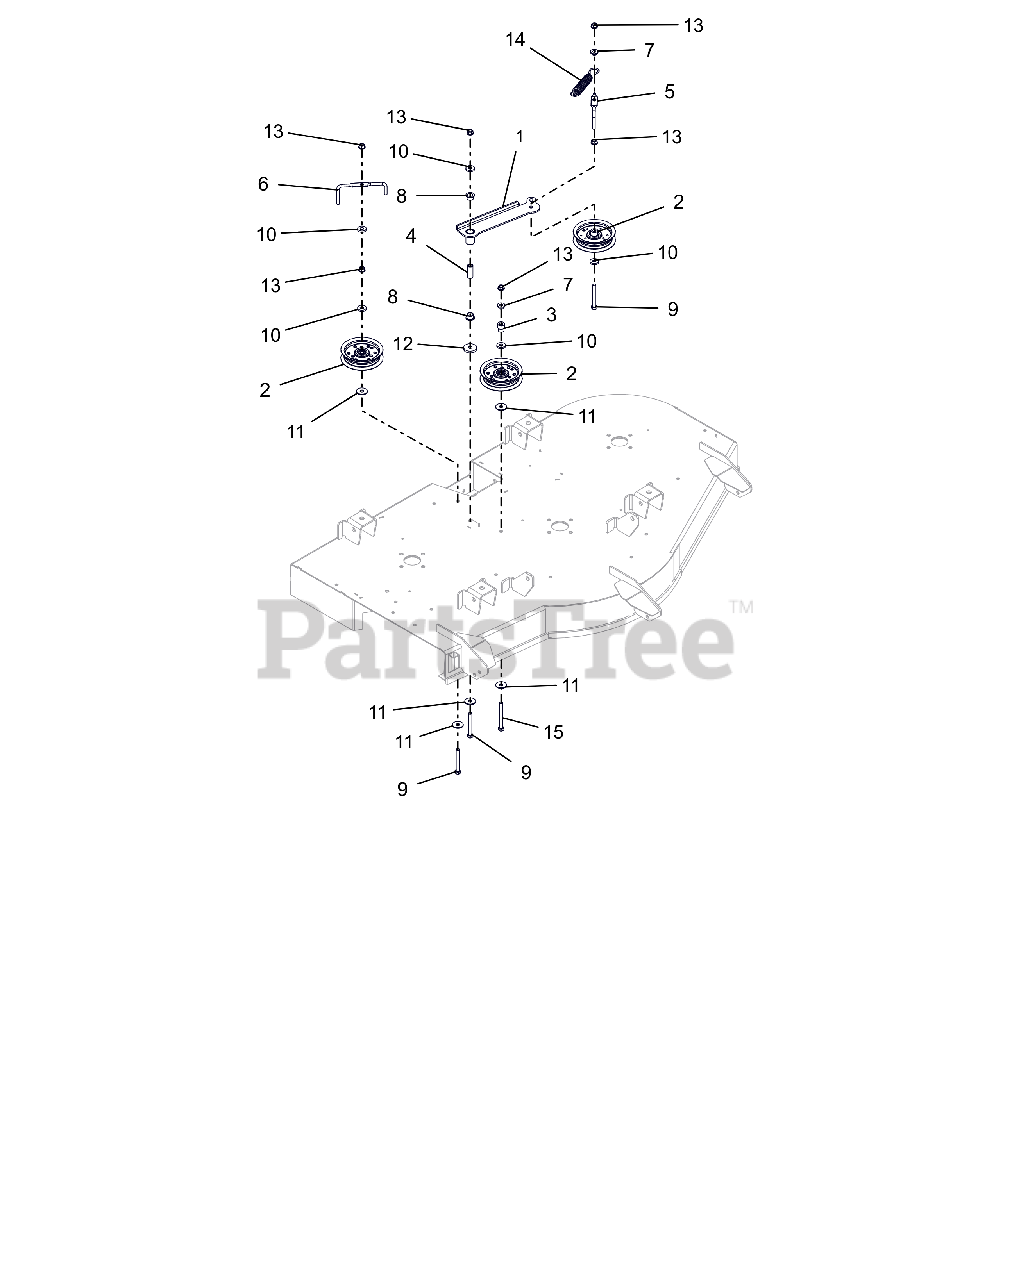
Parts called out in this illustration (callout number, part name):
1	WLDMT, IDLER ARM-52"
2	ASM, IDLER 4"
3	BUSHING, IDLER (P/M)
4	SPACER, .375IDX.625ODX1.66 PM
5	WIREFORM, BELT FINGER
6	WIREFORM, BELT FINGER
7	BSHG-FLG .385X.500X.875X.406
8	BSHG-FLG, .625X.750X.500X1.00
9	BLT, HEX .38-16X3.00F G5 ZCC
10	WSHR, FLT .406X1.00X.188 ZCC
11	WSHR FL STL .406X1.25X.10ZC120
12	WSHR, FLT .406X1.50X.245 ZCC
13	NUT-LK-TOP-FLG .38-16 ZC120
14	SG-TENS .135X.98X6.0 WLD 62
15	BLT, HEX .38-16X3.50 G5 ZCC
